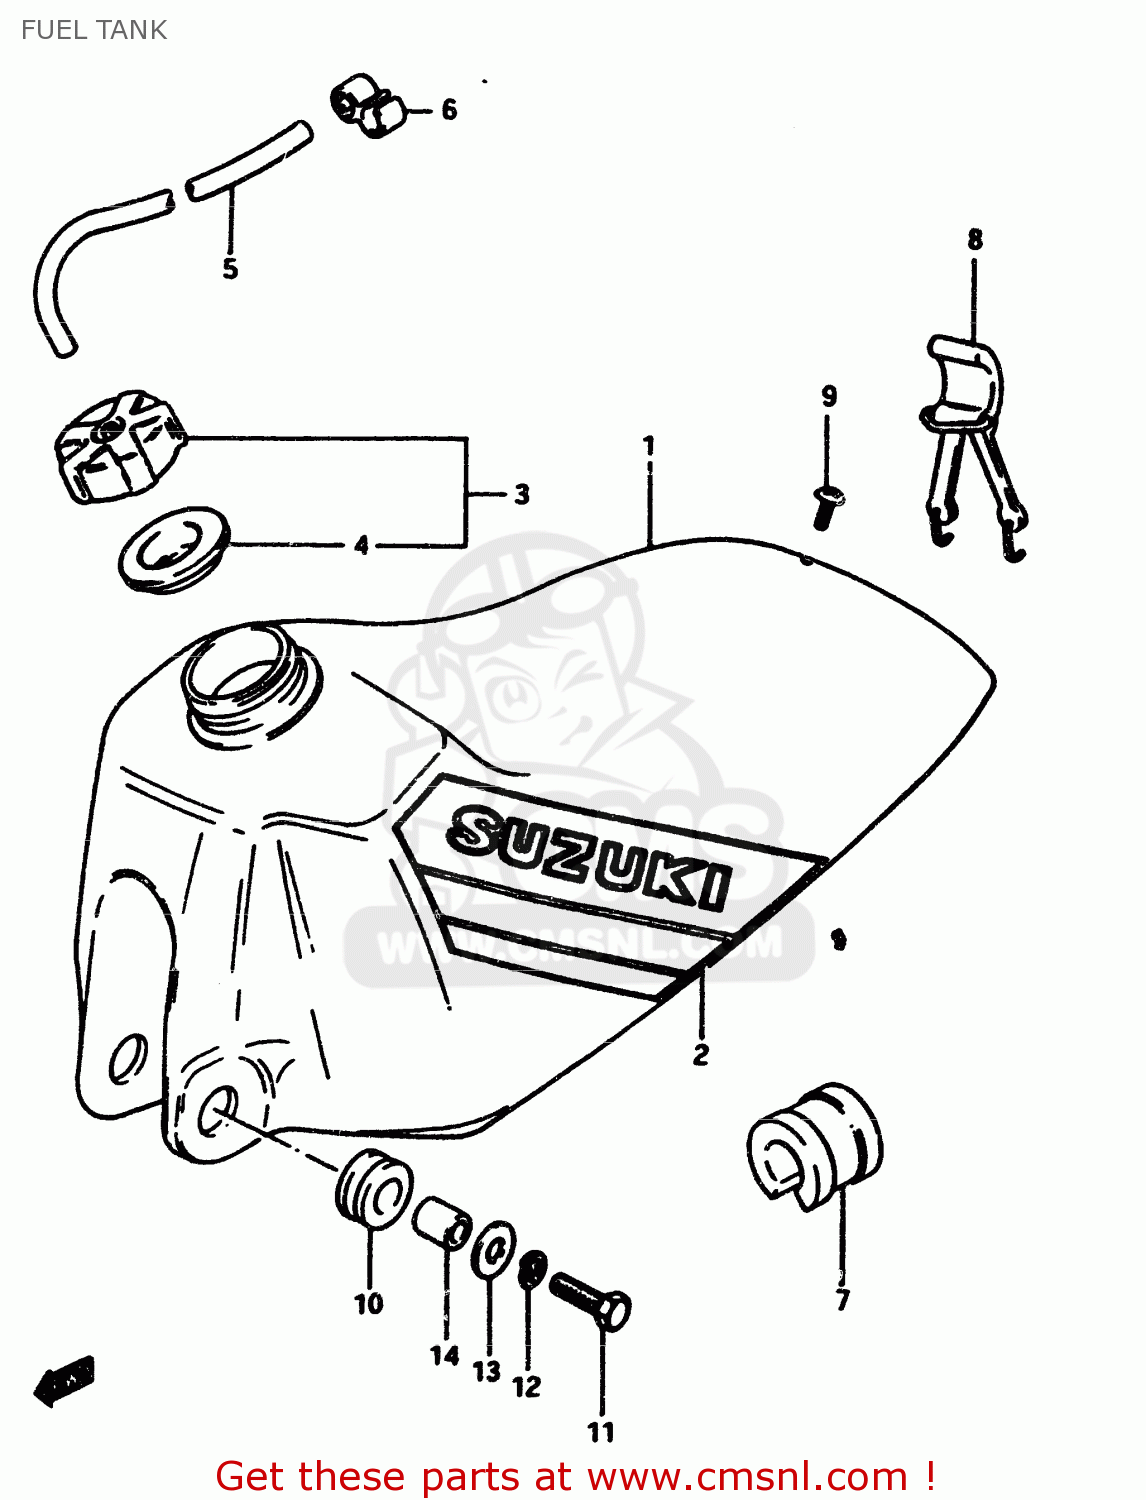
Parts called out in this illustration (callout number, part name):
1	TANK, FUEL (YELLOW)
2	TAPE SET
3	CAP SET,FUEL TANK
4	GASKET,FUEL TANK CAP (NAS)
5	HOSE
6	CLAMP,BREATHER HOSE
7	CUSHION,FUEL TANK UPR
8	BAND,FUEL TANK,REAR
9	SCREW (6X15)
10	CUSHION
11	BOLT
12	WASHER,LOCK,8.
13	WASHER (8.5X26X1.2)
14	SPACER (8.8X12X13.5)
